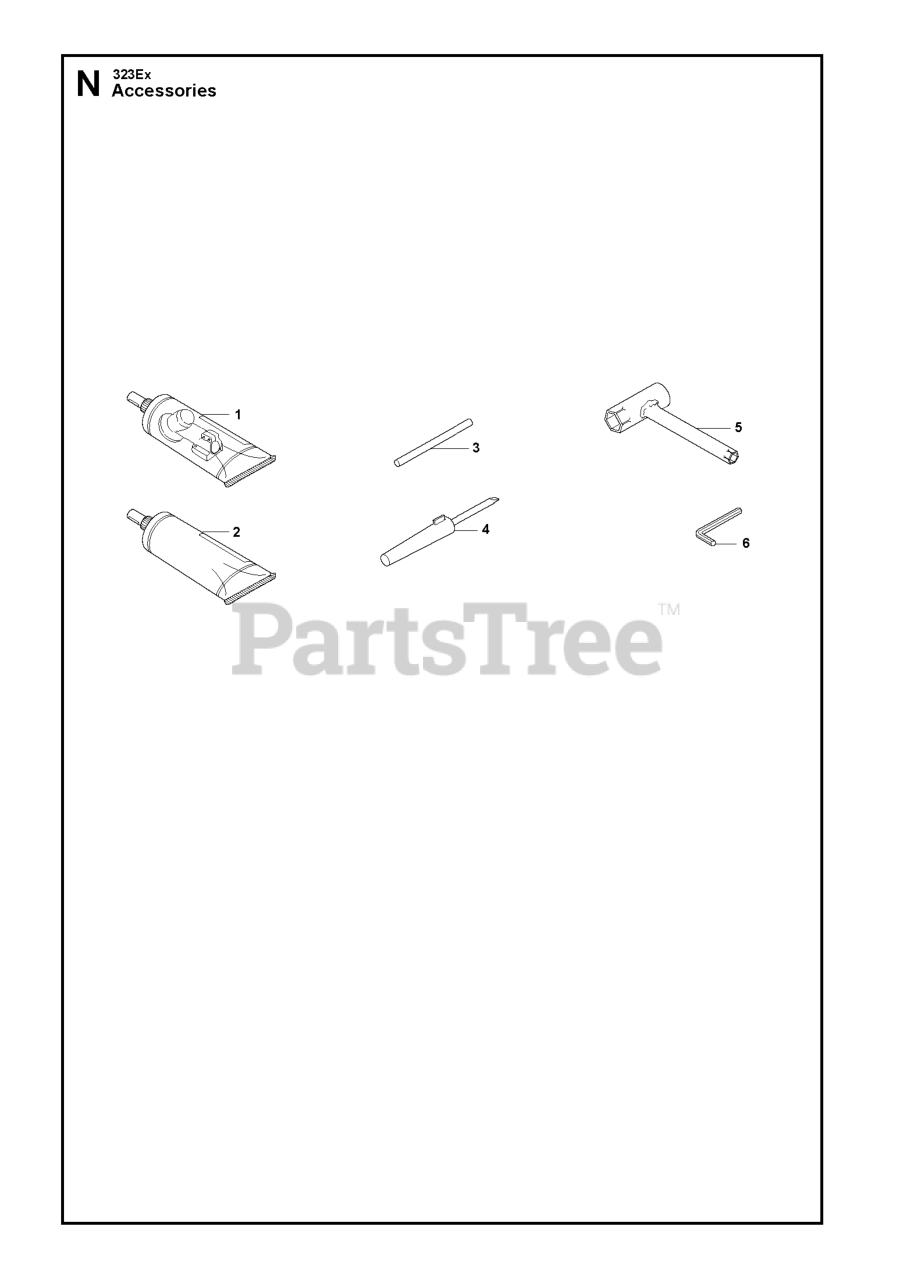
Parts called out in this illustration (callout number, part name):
1	BEVEL GEAR GREASE
2	DRIVE SHAFT GREASE (200 G)
3	LOCKING PIN
4	SCREWDRIVER
5	COMBI WRENCH
6	L-KEY WRENCH
